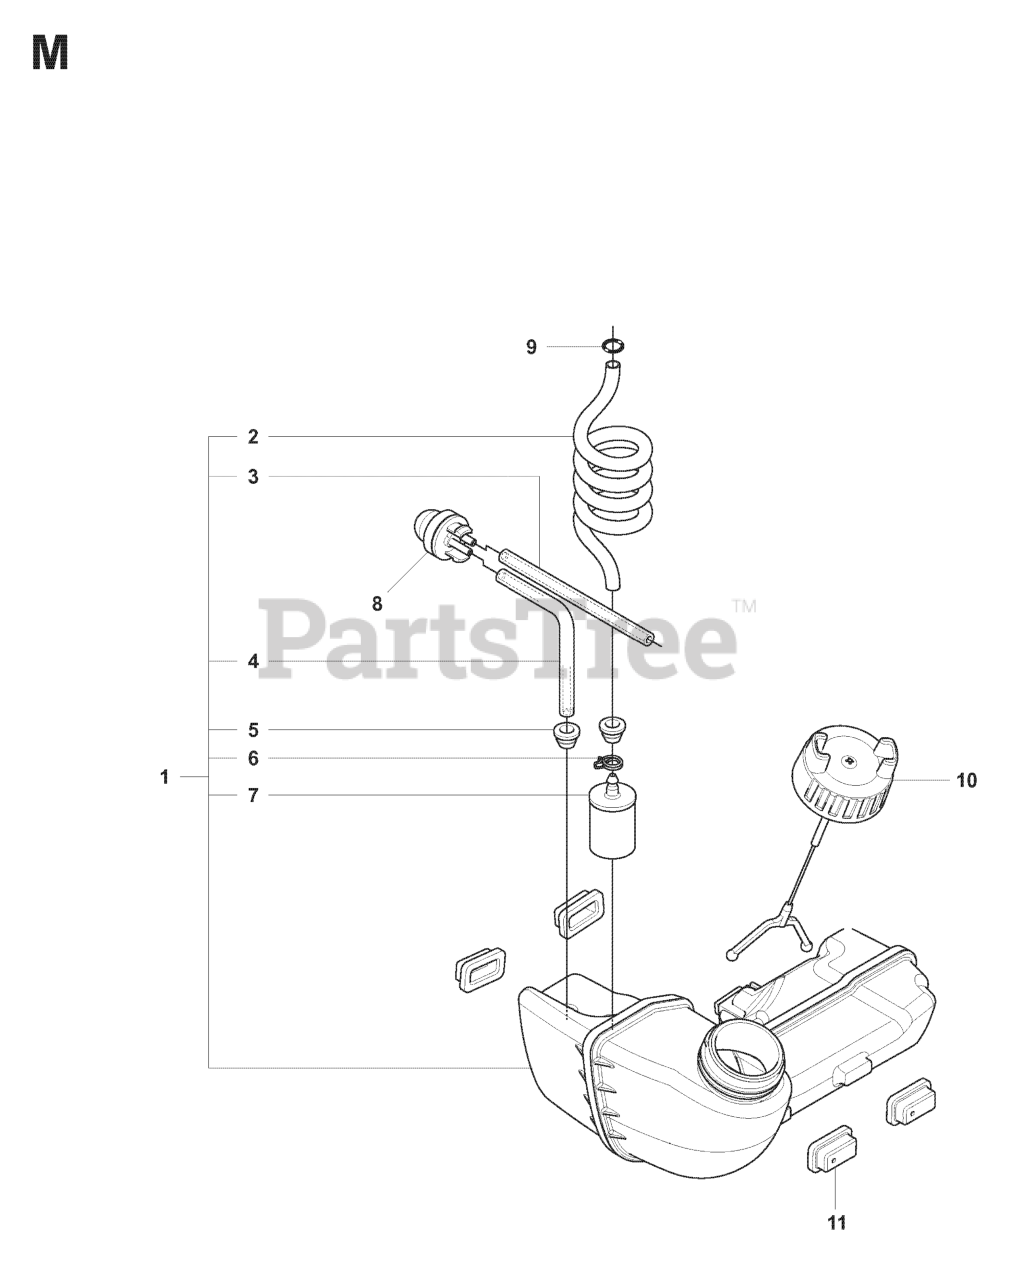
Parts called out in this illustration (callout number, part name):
1	FUEL TANK ASSY
2	FUEL HOSE
3	HOSE.FUEL L=102
4	HOSE.FUEL L=102
5	FUEL TANK BUSHING
6	HOSE CLAMP
7	RP FUEL FILTER
8	AIR PURGE BUBBLE
10	TANK CAP
